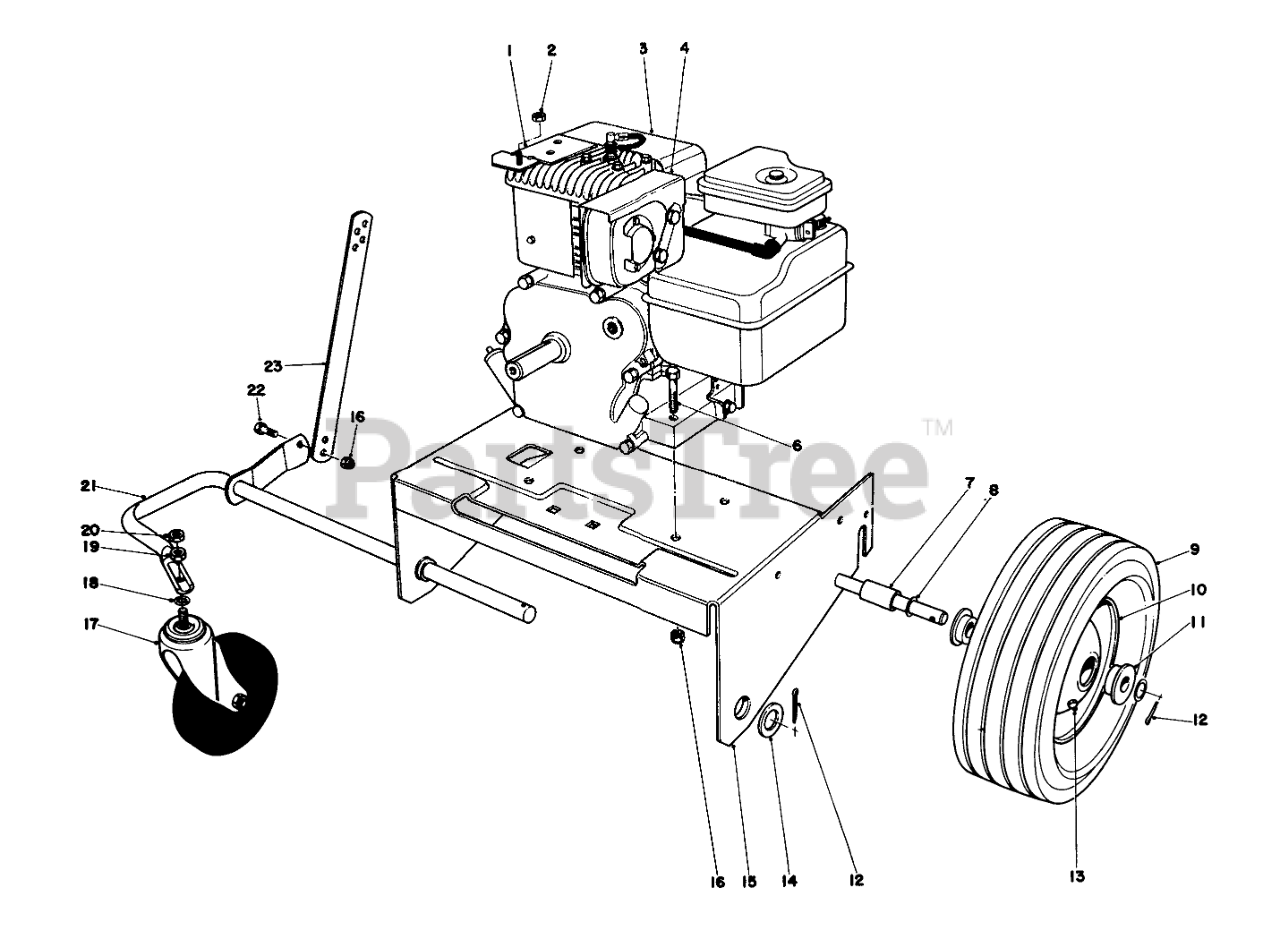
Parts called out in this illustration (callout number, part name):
1	Mounting Bracket
2	NUT-LOCK, NI
3	Engine
4	Heat Shield-Muffler
6	SCREW-HH
7	SPACER-AXLE
8	WASHER
9	Tire
10	Wheel & Tire Assembly (Incl. Ref . #9,11 & 13)
11	BUSHING
12	PIN-COTTER
13	FITTING-GREASE
14	WASHER-FLAT
15	BLWR ENG MTG PLT WA
16	NUT-LOCK, CONE
17	CASTER
18	WASHER-LOCK/INT
19	NUT-HH
20	1/2-13 CONELOCK NUT
21	FRT WHL SUPPORT WA
22	SCREW-HH
23	HT ADJ BAR
